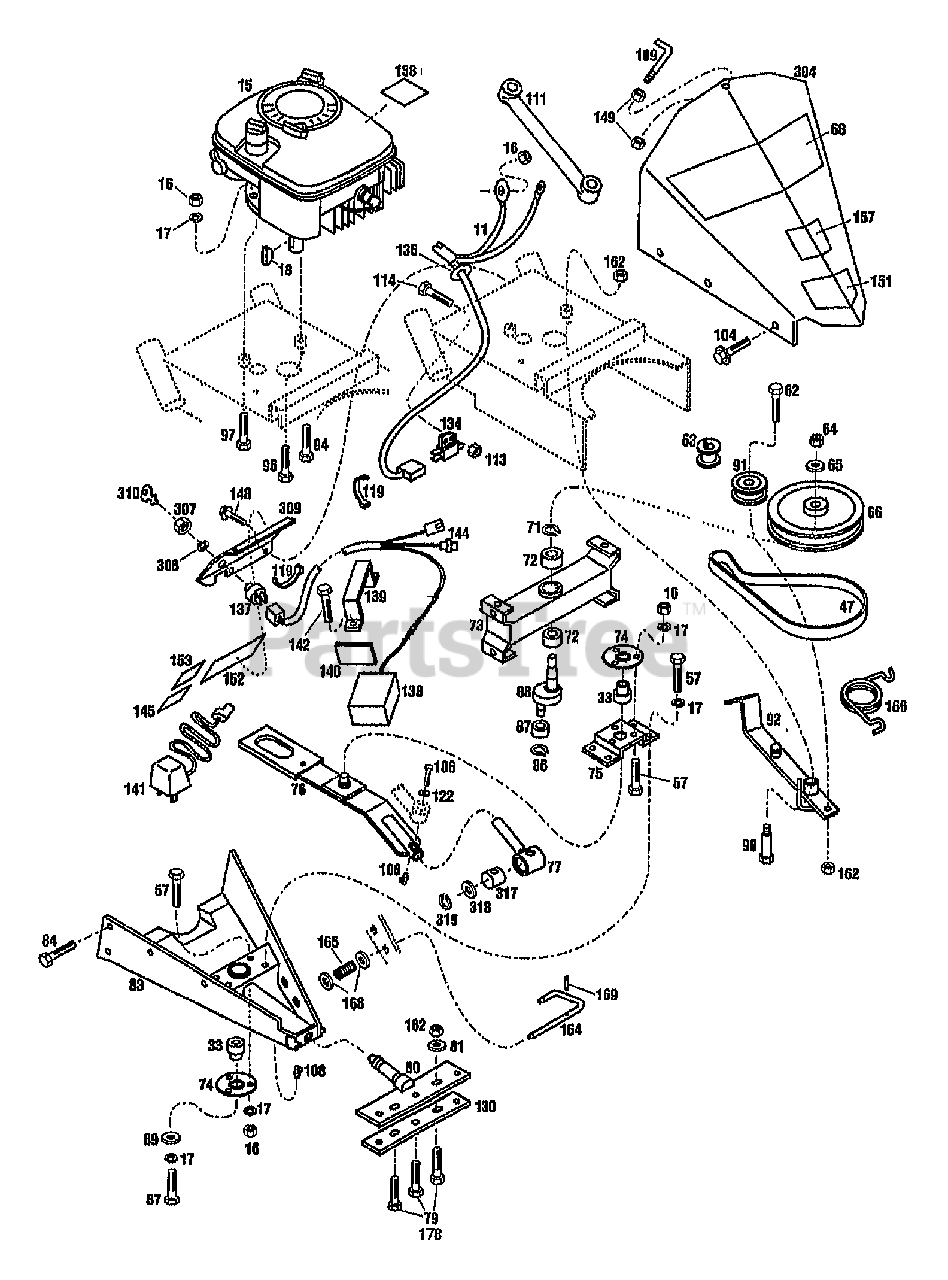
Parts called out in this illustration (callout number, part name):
11	HARNESS-OPERATOR INTERLK (INCL. 119,313-315)
15	ENGINE, BRIGGS & STRATTON, MODEL 12E782, 3. 5 HP (34061)
15	ENGINE, BRIGGS & STRATTON, MODEL 12E782, 4HP (34062)
15	ENGINE, BRIGGS & STRATTON, MODEL 12G782, 5HP (34063)
15	ENGINE, BRIGGS & STRATTON, MODEL 12G787, 5HP W/ELEC. START (34064)
16	NUT-HEX 5/16-18 ZP
17	WASHER-LK .312 INT TOOTH
18	KEY-WOODRUFF .156X.625
33	INSERT-BEARING
57	SCR-HHC 5/16-18X.75 GR 5 ZP
62	SCR-HH 3/8-16X1.5 G5 ZP
63	PULLEY-ENGINE
64	NUT-HEX 5/8-18
65	WASHER-1.305X.649X.098 ZP
66	SHEAVE-ECCENTRIC
68	DECAL-LOGO T/B SICKLEBAR
71	RING-RETAIN EXT .984 ID
72	BEARING-BALL
73	ASSM-HOUSING
74	RETAINER-BEARING ZP
75	SUPT-BEARING UPPER ZP
76	ASSM-ARM ECCENTRIC
77	KIT-KNIFE HEAD & PITMAN (INCL. 317-319)
79	SCR-HFLK 3/8-16X1.25 ZP
80	ASSM-MOUNTING BRKT
81	WASHER-.986X.437X.083 ZP
83	ASSM-FRONT HOUSING
84	SCR-HFLK 5/16-18X.75 ZP
86	RING-RETAIN EXT .669 ID
87	BEARING-ECCENTRIC
88	SHAFT-ECCENTRIC
89	WASHER-.312 X 1.378
90	SCR-SHLDR 3/8-16
91	IDLER-SHEAVE 3" X 1"
92	ASSM-CLUTCH ARM ZP
94	SCR-HH 5/16-18X3.0
96	SCR-HH 5/16-18X4.0 G5 ZP
97	SCR 5/16-18X3.00
104	SCR-HFLK 5/16-18X.625 STH
106	SCR-HH 1/4-20X1.25
108	FITTING-GREASE .25-28X90
109	HOOK-UPPER .25
111	DIVERTER-WEED BUNGI
113	NUT W/LKWASHER 10-24 ZP
114	SCR-HHS 10-24X.625 ZP
119	TIE-CABLE NYLON BLACK
122	WASHER-.75X.312X.065 ZP
130	BRKT-DOUBLER
134	SWITCH
135	GROMMET
137	SWITCH-EL IGNITION {34064}
138	BATTERY ES2.9-12 {34064}
139	CLAMP-BATTERY (WB MOWERS) {34064}
140	PAD-BATTERY {34064}
141	CHARGER-BATTERY {34064}
142	SCR-HFLK 1/4-20 X .375 {34064}
144	HARNESS-START {34064}
145	DECAL-ELEC START ENG {34064}
148	SCR 1/4-20X.5 FL SELF TAP
149	NUT-HF/LK 1/4-20 ZP
151	DECAL-OPEI CAUTION
152	DECAL-WARN.OPER.INST
153	DECAL-AMERICAN LEGEND-SM
157	DECAL-DNG SHARP CUT BLADE
158	DECAL-WARN.HOT SURFACES
162	NUT-H/LK 3/8-16
164	PIN-LOCKING
165	SPRING-COMPRESSION
166	SPRING-TORSION
168	WASHER-FLAT 3/8 SAE
169	PIN-ROLL 1/8 X 3/4
304	HOOD W/DECALS(INCL. 151 & 157)
307	NUT (IGNIT SWITCH) (34064)
308	WASHER-1.0X.64X.029 (34064)
309	PLATE W/DECALS (INCL. 145, 152 & 153)
310	KEY-IGNITION (34064)
317	BEARING-NYLATION
318	WASHER-1.115X.637X.06
319	RING-SNAP
